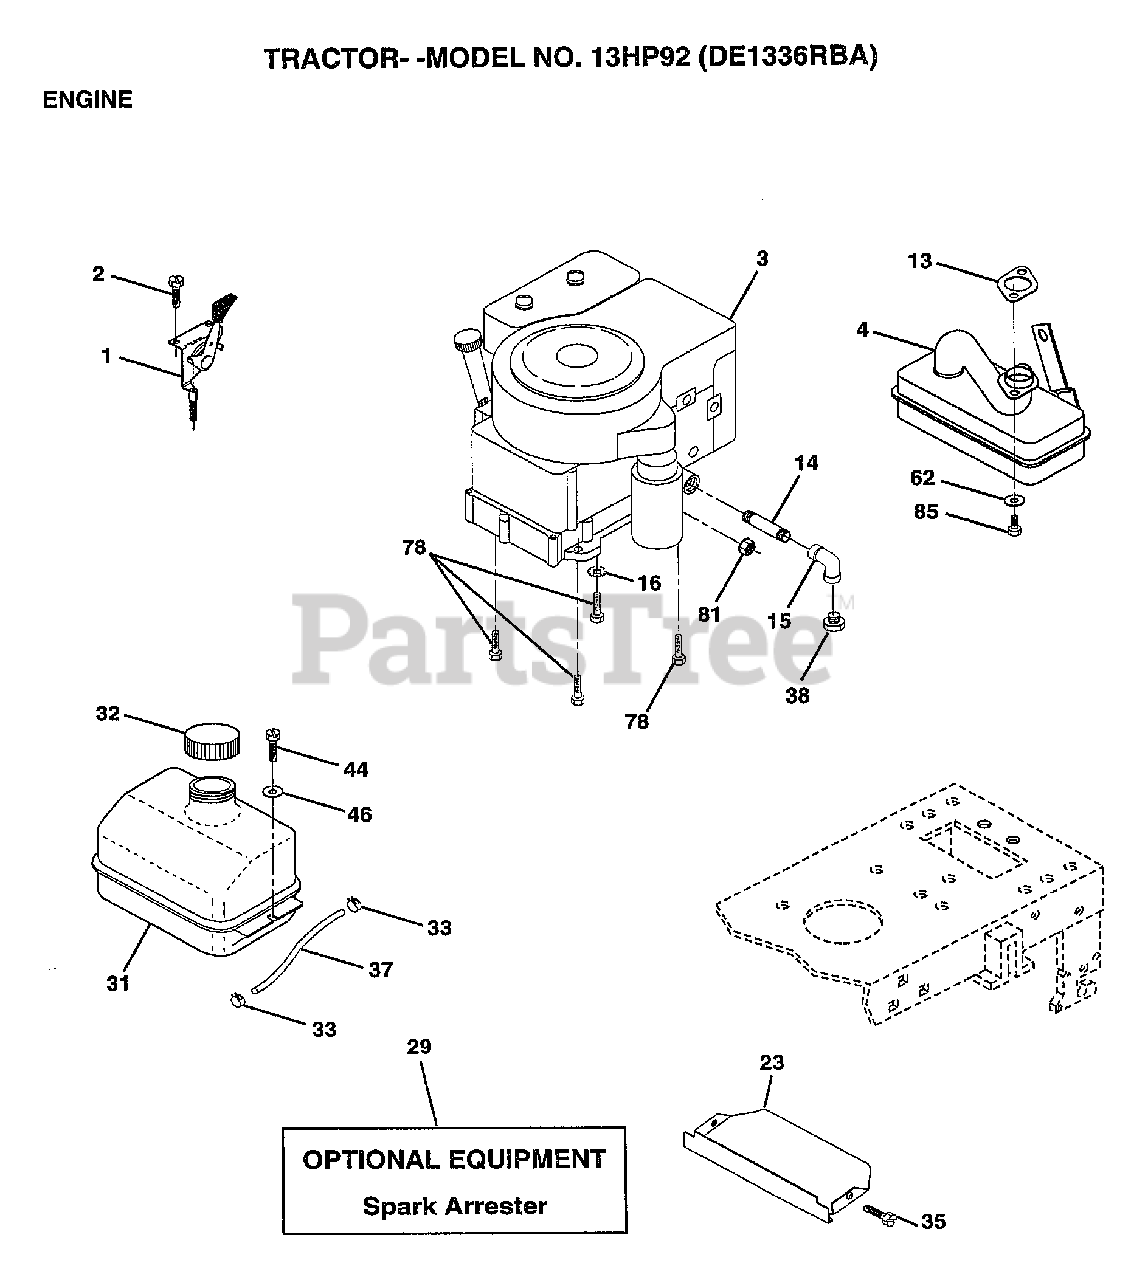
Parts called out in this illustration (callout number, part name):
1	CONTROL-THROT/CHO
2	SCREW LT
4	MUFFLER TEC. 13HP
14	PIPE NIPPLE LT
15	ELBOW
16	LOCKWASHER
23	SHIELD.BRN/DBR.GD
31	TANK.FUEL.LT.
32	CAP ASM FUEL
33	HOSE CLAMP
35	SCREW
37	LINE FUEL
44	SCREW HEX CRT
46	WASHER
62	LOCKWASHER
66	"STOP,DASH THROTT"
72	SCREW
78	SCREW
81	NUT
85	SCREW HEX HD CAP
